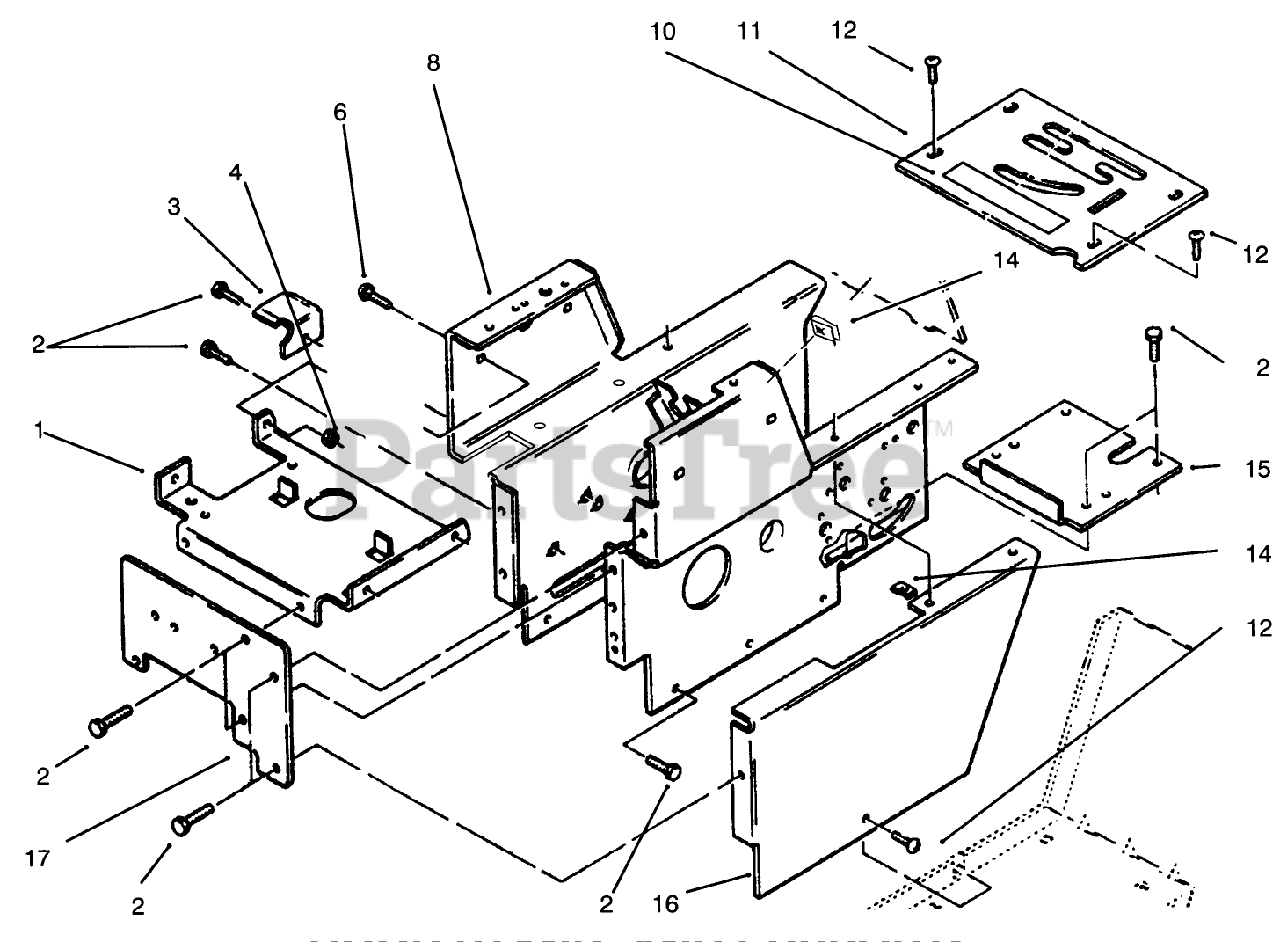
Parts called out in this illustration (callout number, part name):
2	SCREW
10	DECAL-DANGER
11	SHIFT PLATE/DECAL ASM
